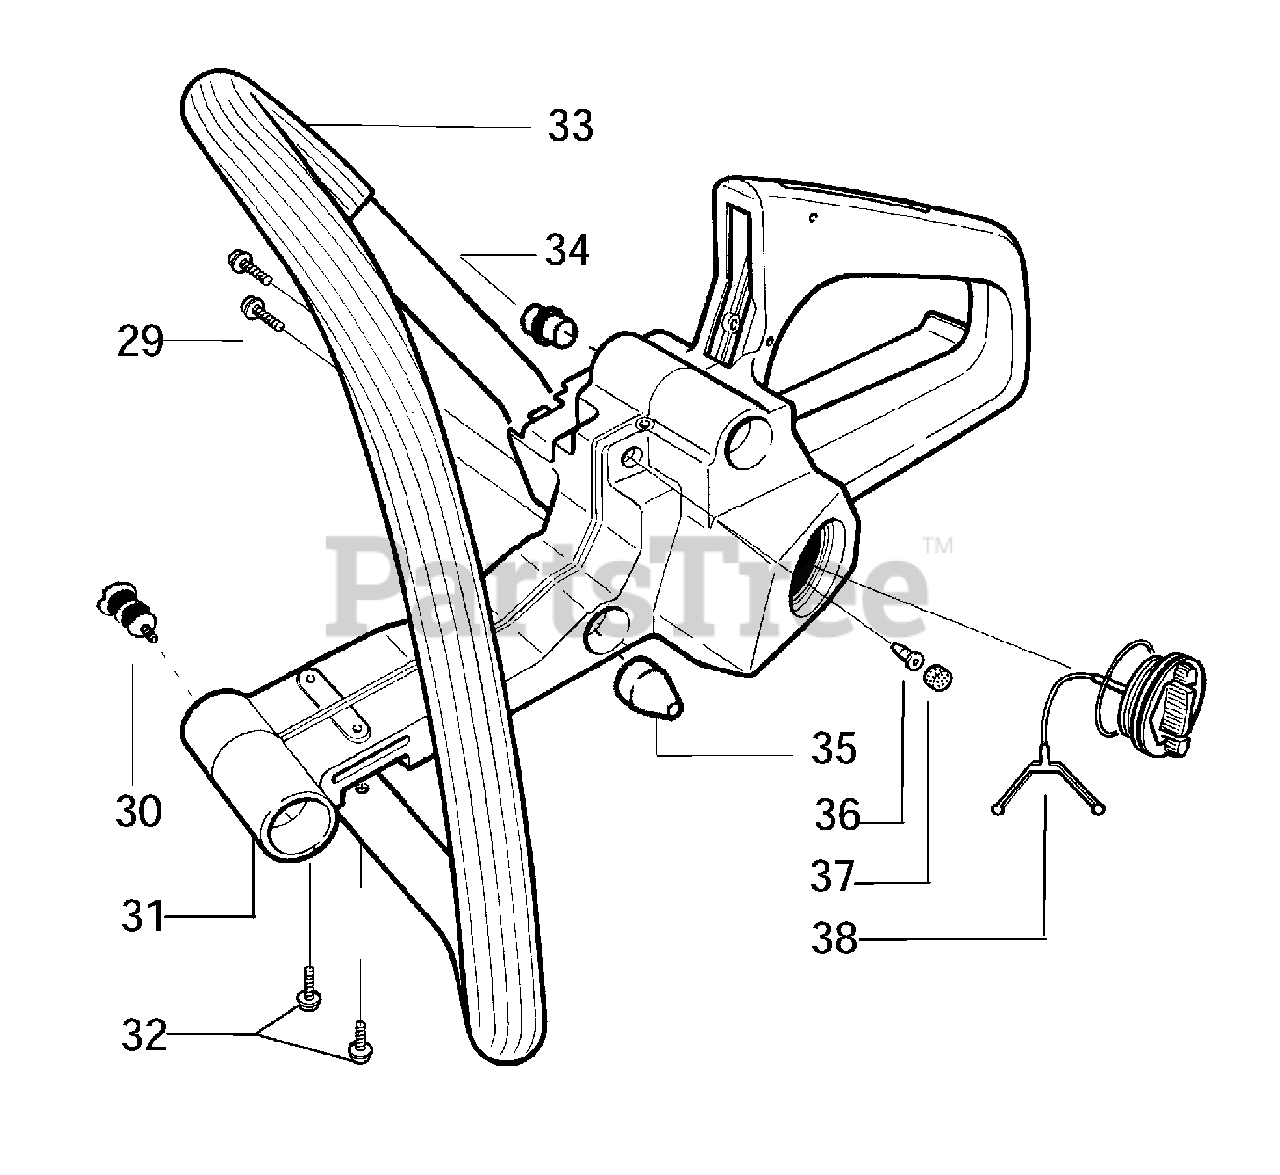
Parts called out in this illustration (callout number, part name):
31	Assy. -Tank/Handle
33	Handle-Front
34	Isolator - Limiter
35	Isolator Bumper
36	Valve - Check
37	Plug - Vent
38	Assy. Fuel Cap
